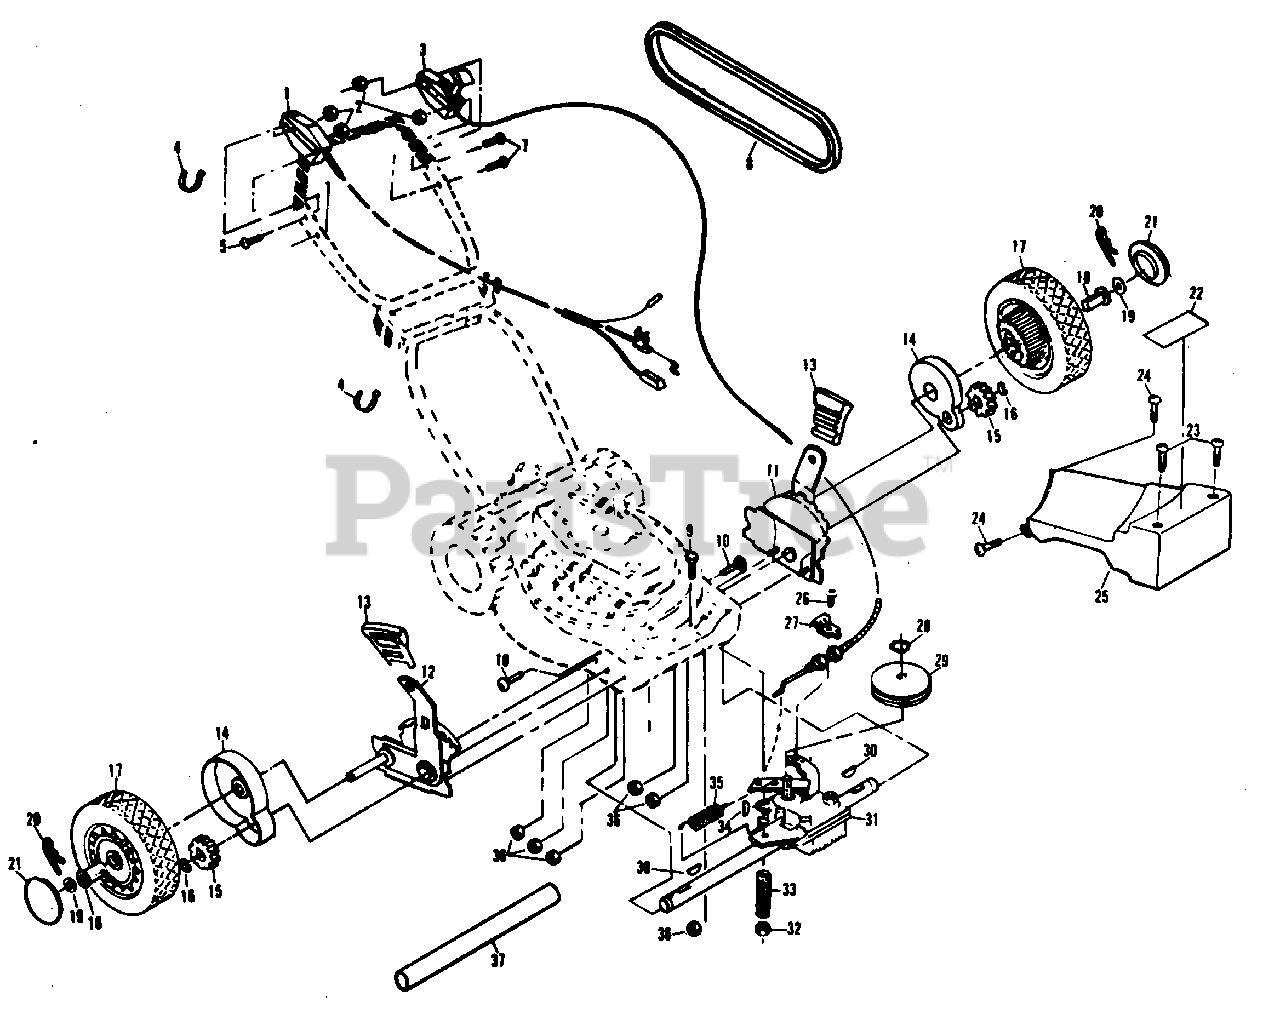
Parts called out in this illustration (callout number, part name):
1	Engine Control Cable (AYP part number)
2	Locknut (AYP part number)
3	Drive Control Cable (Complete) (AYP part number)
4	Wire Tie (AYP part number)
5	Machine Screw (AYP part number)
7	Machine Screw (AYP part number)
9	Hex Head Bolt (AYP part number)
10	Flat Head Machine Screw (AYP part number)
11	Wheel Adjuster Assembly (Left)
12	Wheel Adjuster Assembly (Right)
13	Selector Knob (AYP part number)
14	Dust Cover (AYP part number)
15	Pinion (AYP part number)
16	E-Ring (AYP part number)
17	Wheel & Tire Assembly (AYP part number)
18	Wheel Bushing (AYP part number)
19	Flat Washer (AYP part number)
20	Retainer Clip (AYP part number)
22	Drive Cover Decal (AYP part number)
23	Pan Head Tapping Screw (AYP part number)
24	Hex Washer Head Screw (AYP part number)
25	Drive Cover (AYP part number)
26	Hex Washer Head Tapping Screw (AYP part number)
27	Cable Clamp (AYP part number)
28	Retaining Ring (AYP part number)
29	Drive Pulley (AYP part number)
30	Woodruff Key #3 (AYP part number)
31	Gear Case Assembly Kit (AYP part number)
32	Locknut (AYP part number)
33	Spring (AYP part number)
34	Woodruff Key #213 (AYP part number)
36	Locknut (AYP part number)
37	Drive Shaft Cover (AYP part number)
